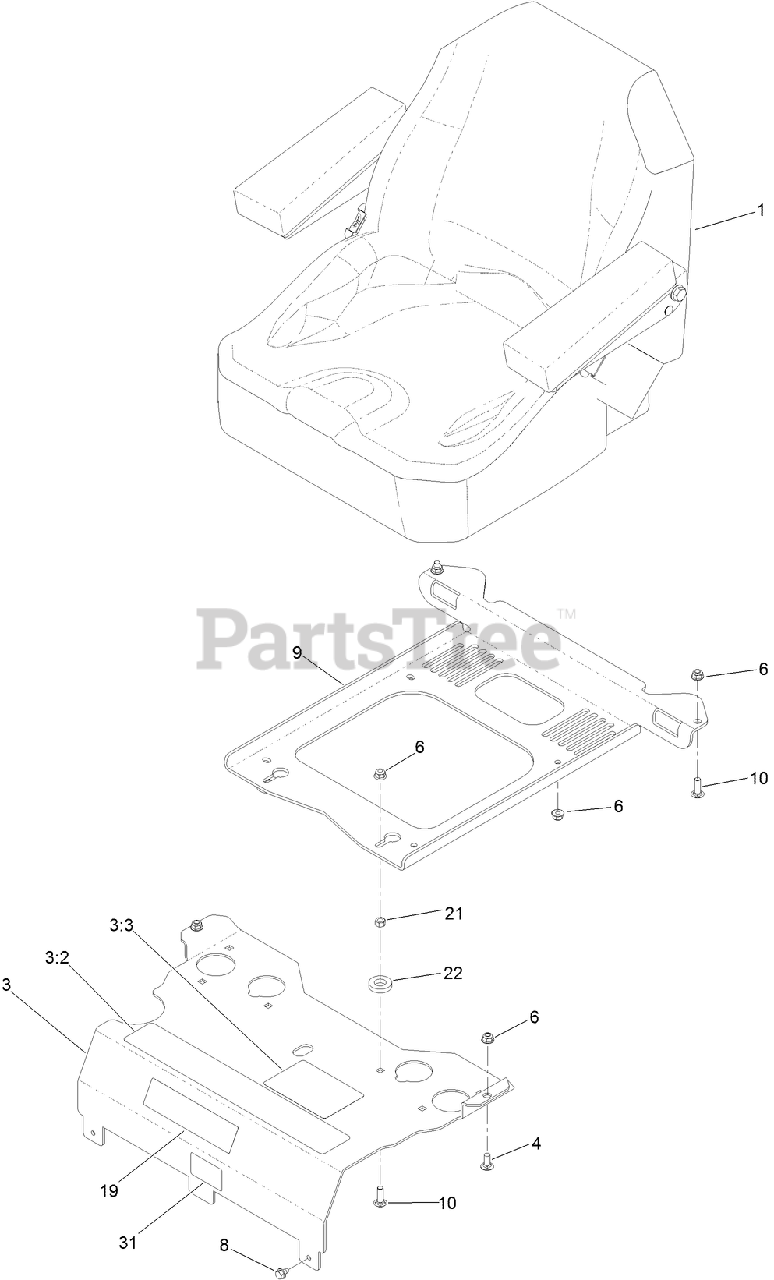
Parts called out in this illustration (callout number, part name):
1	SEAT ASM
3	SEAT MOUNT ASM
3:2	DECAL-CONSOLE
3:3	DECAL-SERVICE AID
4	SCREW-CARR
6	NUT-HF, NI
8	SCREW
9	PLATE-SUPPORT, SEAT
10	SCREW-CARR
21	NUT-HEX
22	SPACER
31	DECAL-EFI
